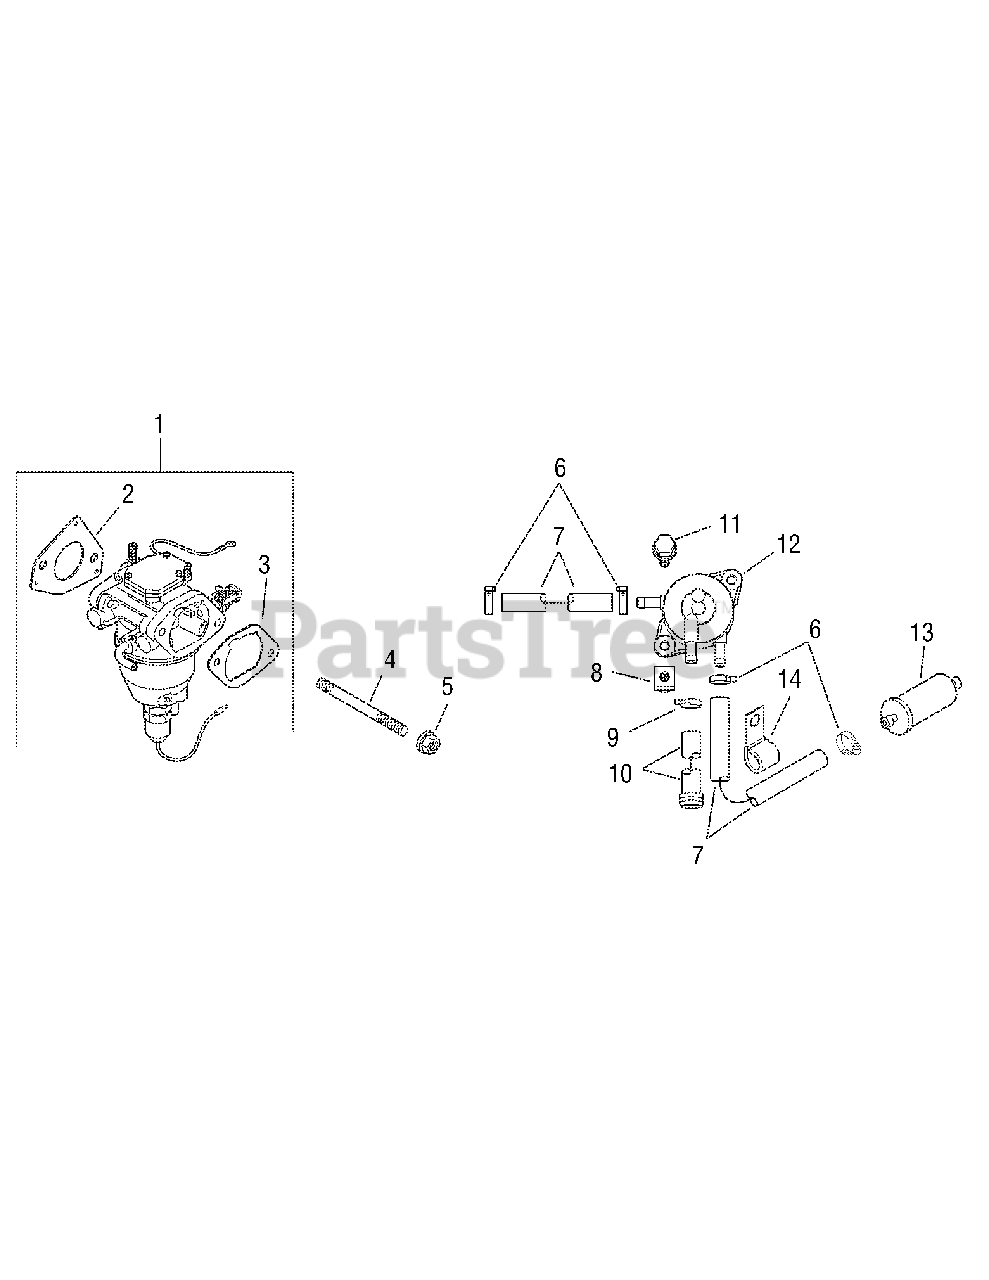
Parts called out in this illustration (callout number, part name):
1	Kit, carburetor w/gaskets (Includes 2,3)
2	Gasket, carburetor
3	Gasket, air cleaner base
4	Stud, carburetor
5	Nut, hex. flange M6x1.0
6	Clamp, hose
7	Line, fuel (Fuel line comes in lengths of 24")
8	Nut, plastic
10	Hose, fuel pump
11	Screw, hex. cap M6x1.7x18
12	Pump, pulse fuel
13	Filter, fuel
